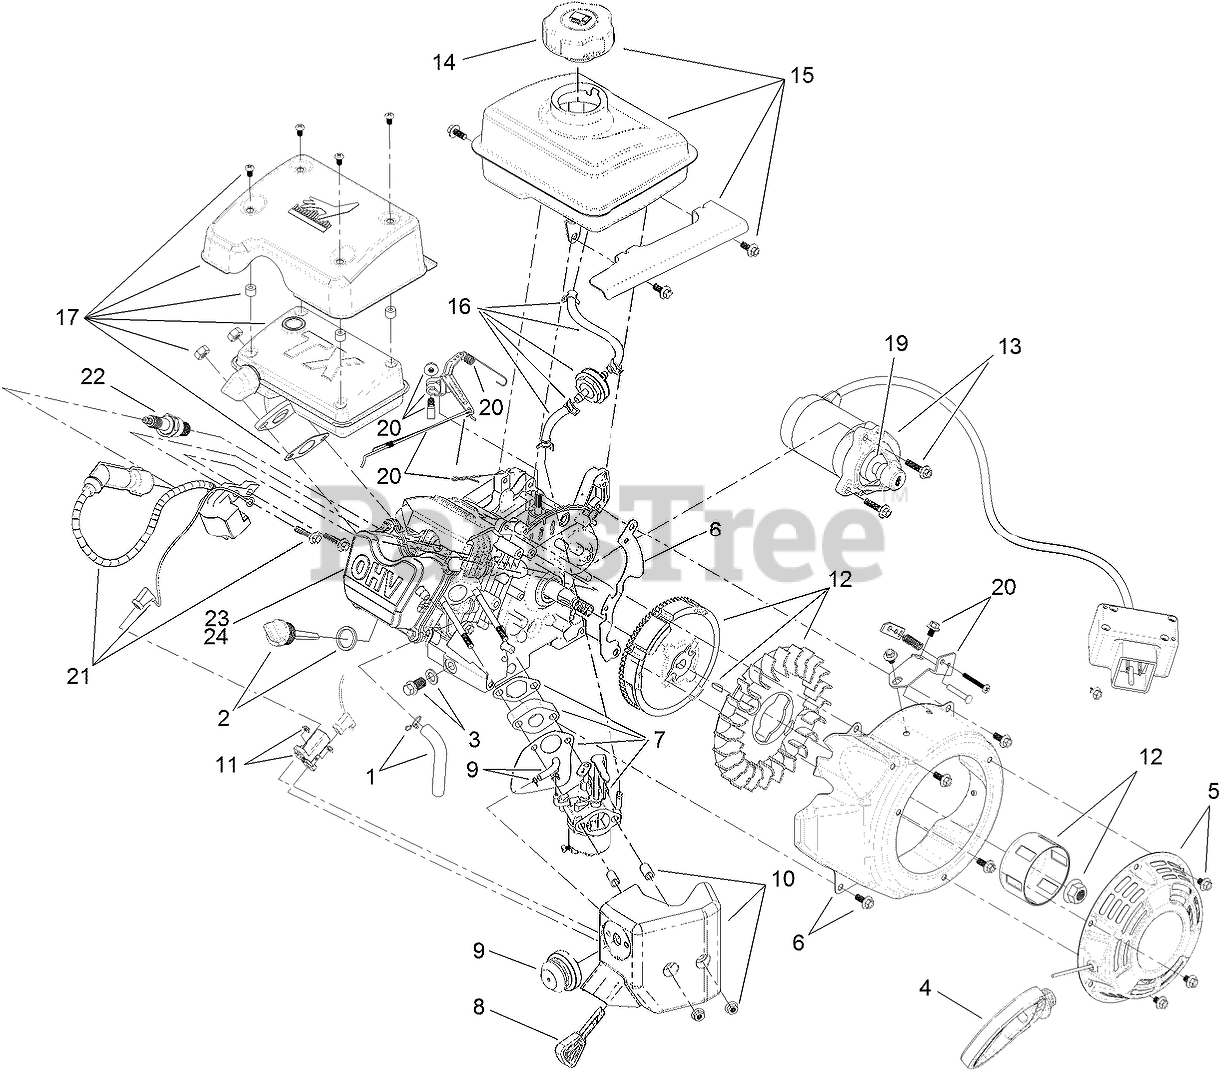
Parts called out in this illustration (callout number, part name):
1	BREATHER TUBE KIT
2	DIPSTICK AND O-RING KIT
3	DRAIN PLUG KIT
4	MITTEN GRIP KIT
5	RECOIL ASM KIT
6	BLOWER SHROUD KIT
7	COMPLETE CARB SERVICE KIT
7	CARB FLOAT AND NEEDLE KIT
8	KEY AND LANYARD KIT
9	PRIMER BULB KIT
10	HEATER BOX KIT
11	SWITCH KIT
12	FLYWHEEL KIT
13	ELECTRIC STARTER KIT
14	FUEL CAP ASM KIT
15	FUEL TANK, CAP AND HARDWARE KIT
16	FUEL LINE, FILTER AND CLAMP KIT
17	MUFFLER KIT
19	PINION KIT
20	GOVERNOR ARM, SPRING, LINK, HARDWARE KIT
21	IGNITION KIT
22	SPARK PLUG
23	VALVE COVER ASM
24	GASKET-COVER, VALVE
